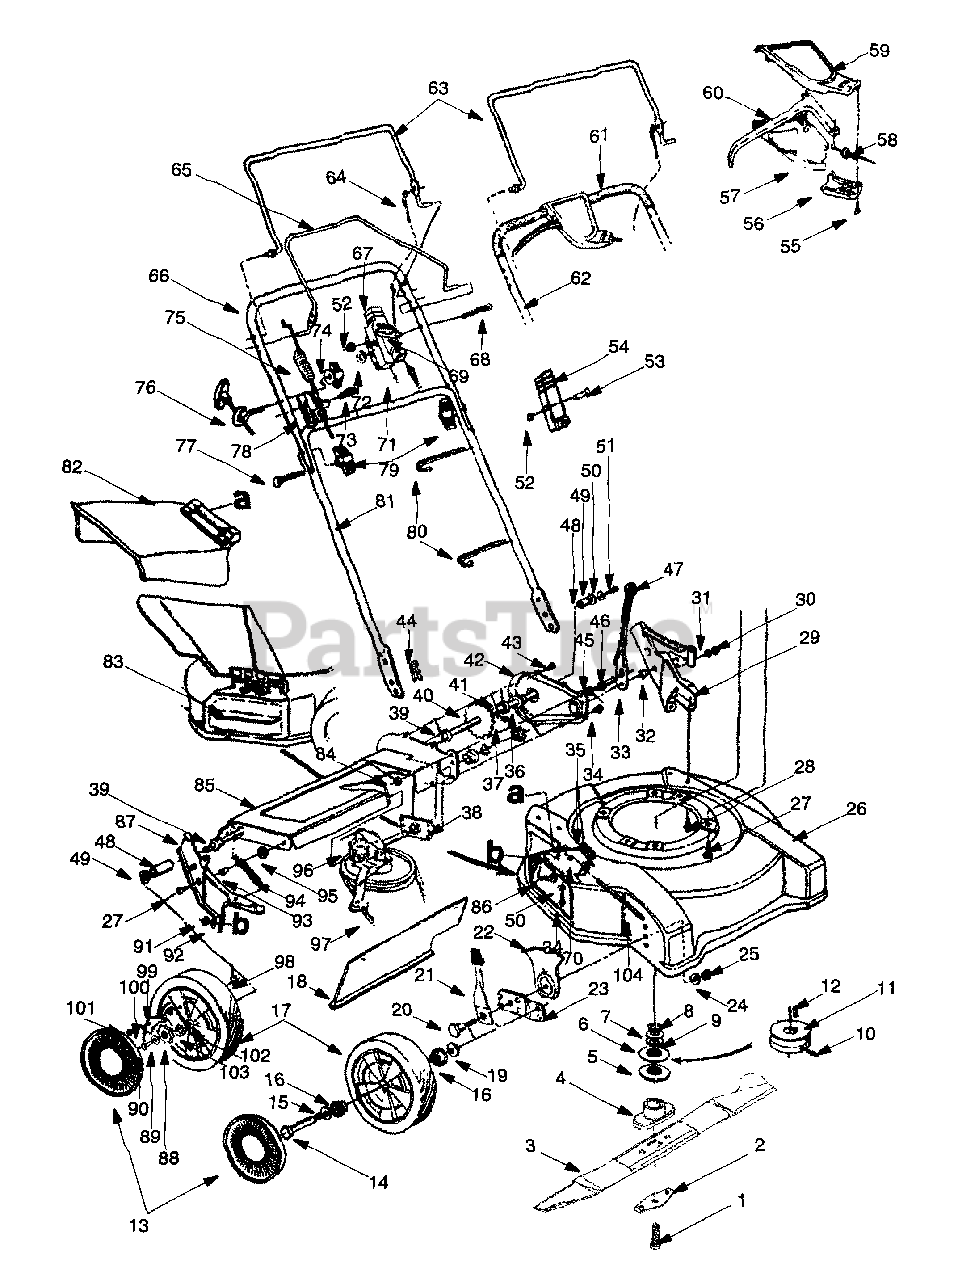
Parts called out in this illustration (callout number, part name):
1	Hex Bolt 3/8-24 x 1.5" Lg.
2	Blade Bell Support
3	22" Blade
4	Blade Adapter w/star
5	Lower Pulley Half
6	Upper Pulley Half
7	Spr. Wash. .89 I.D.
8	Crankshaft Spacer
9	Fl-Wash. .885 I.D.
10	Set Scr. #10-32 x .25" Lg.
11	Keyed Pulley (234)
12	Sq. Key, Square, 3/16 x 1/2
13	Hub Cap, Euro, Grey 3-1/2" Dia.
14	Shld. Bolt .498" Dia. x 1.45"
15	Wave Wash. .51" I.D. x.78"
16	Wheel Bearing
17	Wheel Assembly
18	Rear Flap
19	Bell-Wash. .38" I.D. x .88"
20	Shld. Bolt .5" Dia. x .357
21	Spring Lever Ass'y. w/Knob
22	Height Adj. Plate
24	Bell Wash. .39 I.D. x 1.38 O.D.
25	Hex Nut 3/8" x 16
28	Hex Wash. Hd. 8-Tap Scr. 5/16-18
31	Fl-Wash. .385" I.D. x .87"
32	Shld. Spacer .5" Dia.
33	Height Adj. Lever
34	Hex Self-Tap Scr. 1/4-20 x .5"
35	Torsion Spring
36	Hex Flange Bearing
37	#48 Chain .5" Pitch x 30 Links
39	Hex Flange Bearing
40	Rear Shaft Ass'y. 21.94" Lg.
41	Fl-Wash. .531" I.D. x .93"
44	Hairpin Clip
45	L-Wash. 3/8" I.D.
46	Shld. Pin 3/8-24 x 1.43" Lg.
48	Spacer .513" I.D. x .703"
49	Fl-Wash. .531" I.D. x .93"
50	Bell-Wash. 1/4" I.D.
51	Hex Bolt 1/4-20 x .62" Lg.(Grade 5)
52	Hex L-Nut 1/4-20 Thd.
53	Machine Screw 1/4" x 20
54	Cable Housing w/o Throttle
55	Screw #10-16 x .625"
56	Mounting Cap
57	Control Cover-Lower Half
58	S.P. Cable (Single Bail)
59	Control Cover-Upper Half
60	Control Lever
61	Foam Grip
64	Control Cable 39" Lg.
68	Oval C-Sunk Screw
69	Throttle Lever
70	Adapter Plate
71	Throttle Cable 55" Lg.
72	Spring Washer .66" I.D.
73	Hex Wash. AB-Tap Scr. 5/16 x .75" Lg.
74	Handle Knob 1/4-20 Thd.
75	Drive Cable-41.5" Lg. (Dual Bail)
76	Rope Guide
77	Curved Hd. Bolt 5/16-18 x 2"
78	Cable Bracket
79	Hand Knob
80	Cable Tie
82	Chute Deflector Ass'y.
83	Mulching Baffle
84	Hex Jam Nut 3/8-24 Thd.
89	Bell Washer .265 ID x .75
90	Cap Screw HH 1/4-20 x .620
91	L-Wash. 5/16" I.D.
92	Bell-Wash. 5/16" I.D.
93	Spacer .383" I.D. x .503"
94	Ext. Spring .5" O.D. x 3.8" Lg.
95	Fl-Wash. .385" I.D. x 1" O.D.
96	Transmission Comp
97	"V"-Belt
98	Weld L-Nut 1/4-20 Thd.
99	Pawl-R.H.
100	Spring-Nylon
101	Shld. Scr. .342" Dia. x .268"
102	Sleeve Brg. 1/2" I.D.
103	Pawl Plate
104	Hinge Pin
